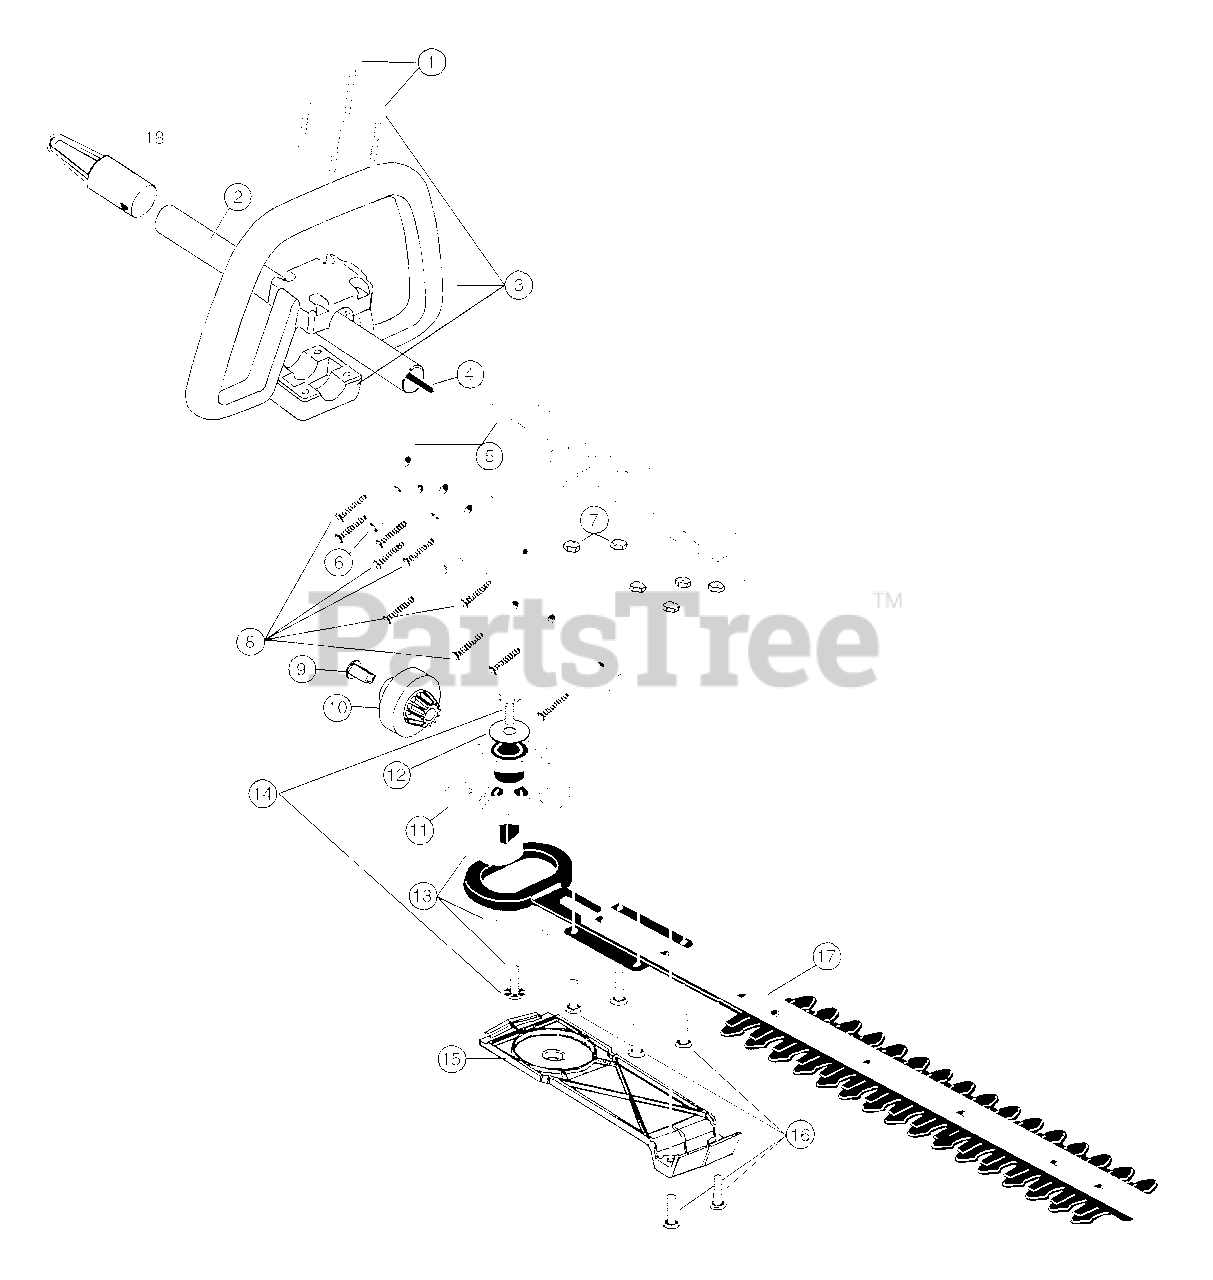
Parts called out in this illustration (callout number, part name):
2	Drive Shaft Housing Assembly
3	Loop Handle Assembly
4	Drive Shaft Assembly
5	Housing Set
6	Anti-Rotation Screw
8	Housing Screw
9	Insulator
10	Pinion Gear
11	Bevel Gear Assembly
13	Cam Assembly
15	Bottom Plate
17	Cutting Blade Assembly
18	Hanger
